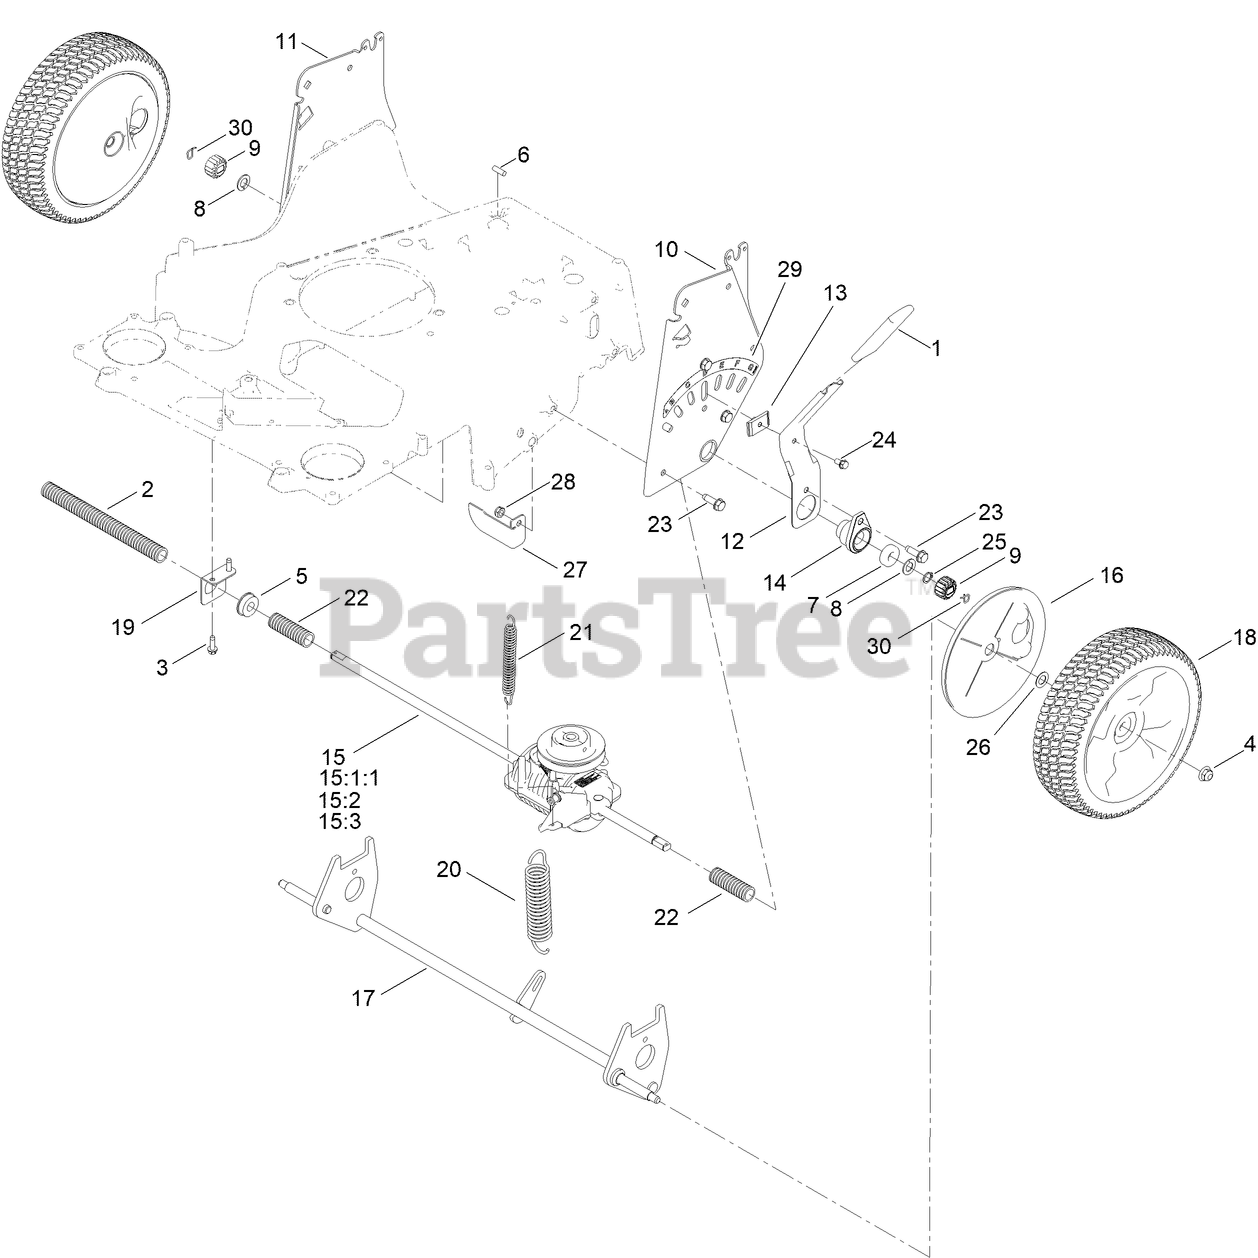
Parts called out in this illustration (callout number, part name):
1	GRIP-LEVER, LIFT
2	CONDUIT-CONVOLUTED
3	SCREW-HWHTF
4	NUT-HF, NI
5	BEARING-BALL
6	PIN-STOP
7	BEARING-BALL
8	WASHER-THRUST
9	GEAR-PINION, 15T
10	PLATE-HOC, LH
11	PLATE-HOC, RH
12	ARM-SPRING
13	KEY-SPRINGARM
14	RETAINER-BEARING
15	TRANSMISSION KIT
15:1:1	TRANSMISSION PULLEY KIT
15:2	PIN-SNAP
15:3	RING-RETAINING
16	COVER-GEAR
17	REAR AXLE ASM
18	10 INCH WHEEL GEAR ASM
19	MOUNT-BEARING
20	SPRING-EXTENSION
21	SPRING-EXTENSION
22	CONDUIT-CONVOLUTED
23	SCREW-THD ROLL, HWH
24	SCREW-HWH
25	RING-RETAINING
26	WASHER-PLAIN
27	BRACKET-STOP
28	NUT-HEX
29	DECAL-HOC, REAR
30	PIN-SNAP
